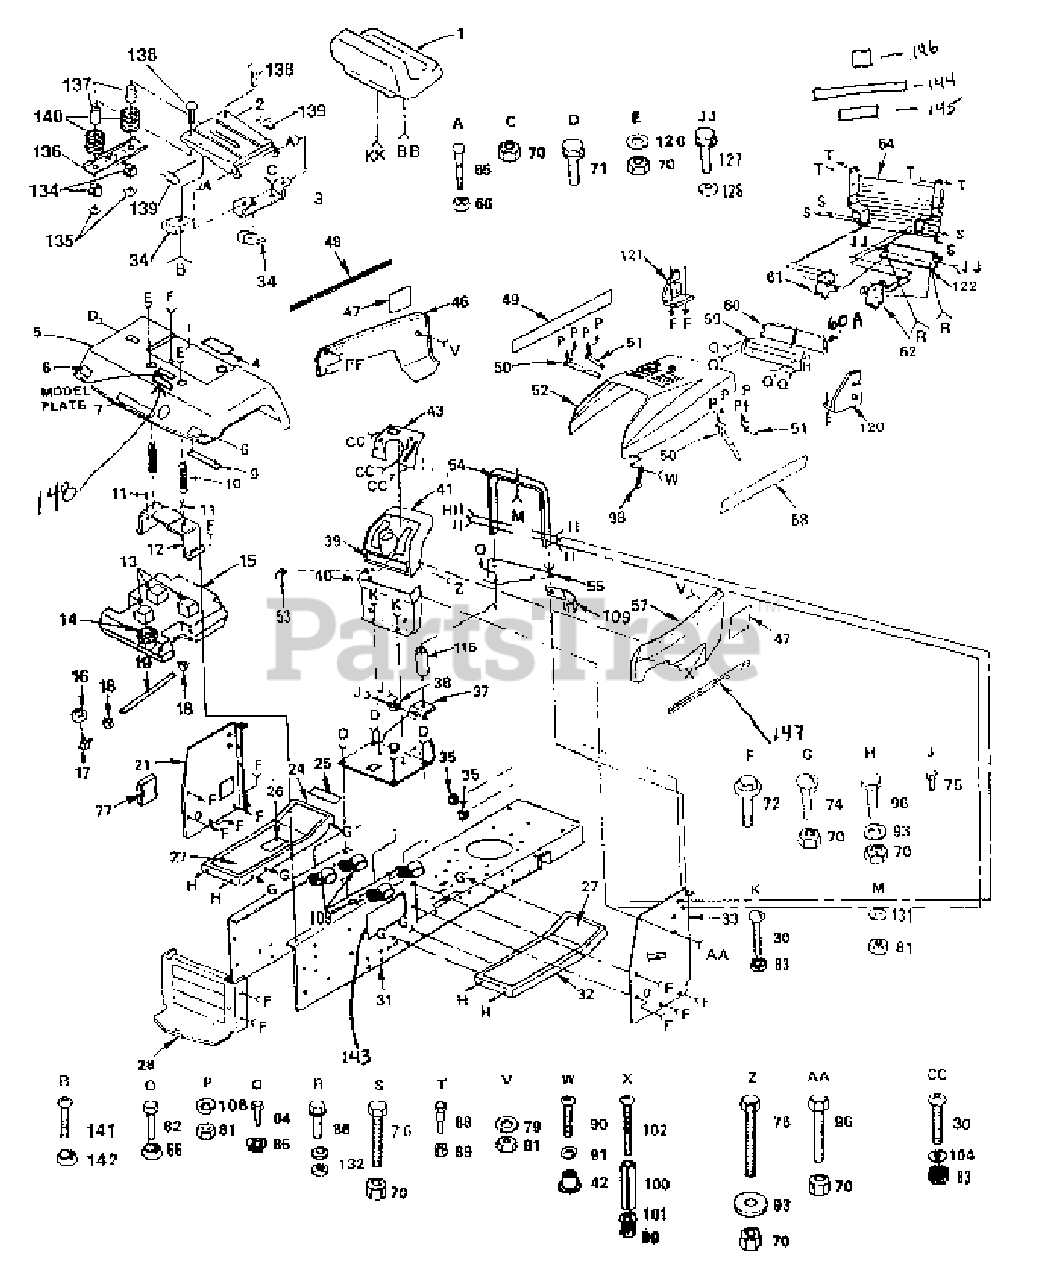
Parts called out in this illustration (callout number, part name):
1	Seat
2	Pan - Seat
3	Bracket - Pivot, Seat
4	Decal - Caution
6	Reflector.Tail Light
7	Decal - Fender
9	Strap - Fender
10	Spring - Compression.Seat
11	Nut - Push
12	Bracket - Fender
13	Pad - Spacer
14	Cap - Fuel
15	Tank - Fuel
17	Stem -Tank, Fuel
18	Clamp - Hose
19	Line - Fuel
21	Panel - Dash, L.H.
24	Footrest- L.H.
25	Decal - Clutch/Brake
26	Decal - Drive Belt
27	Pad - Footrest
28	Drawbar
32	Footrest - R.H.
33	Panel - Dash, R.H.
34	Clip- Insulated
35	Grommet
37	Saddle.
38	Bushing - Steering
39	Decal - Instructions.Caution
40	Dash Assembly - Lower
41	Dash
42	Nut-Weld
43	Plate - Dash
46	Panel - Side, L.H.
47	Decal - Side Panel HWTH140
49	Decal- Hood L.H.
50	Strap Assembly - Hinge, Rear
51	Strap Assembly - Hinge, Front
52	Hood
53	Plug - Button
54	Support.Dash
55	Plate - Support, Battery
57	Panel - Side, R.H.
58	Decal - Hood, R.H.
60	Lens, L.H.
60A	Lens, R.H.
61	Support - Grill, L.H.
62	Support, Grill, R.H.
64	Grill Assembly
65	Bolt-Shoulder 5/16- 18
74	Bolt - Carriage 3/8-16 x 3/4
77	Cover - Access
79	Washer 9132 x 314 x 16 Ga.
90	Screw - Pan Hd. Machine No.10-24 1/2
93	Washer 13/32 x 13/16 x 12 Ga.
98	Latch - Hood
99	Nut -Keps 10-24
100	Spacer - Split 10 x 3/4
101	Washer 7/32 x 1/2 x 18 Ga.
104	Washer 11/32 x 11/16 x 16 Ga.
113	Bolt - Shoulder 5/16 - 18
114	Washer 15/32 x 1 x 16 Ga.
120	Bracket Assembly, R.H.
121	Bracket Assembly, L.H.
123	Adjustment Knob
124	Washer 17/32 x 1-3116 x 12 Ga.
125	Lockwasher 3/8 Ext. Tooth
126	Washer 13/32 x 1 x 14 Ga.
128	Washer 9/32 x 3/4 x 16 Ga.
129	Lockwasher Ext. Tooth
130	Wingnut
131	Washer, 1/4 Ext. Tooth
134	Bushing, Snap.80
136	Bracket, Switch Mount
137	Spacer, Split .28 x .88
139	Foam Strip
140	Spring. Compression
143	Decal, Frame
144	Decal, Grill Stripe
145	Decal, Grill, Husq.
146	Decal, Grill, Husq.
147	Decal, Side Panel
148	Decal, Certification
